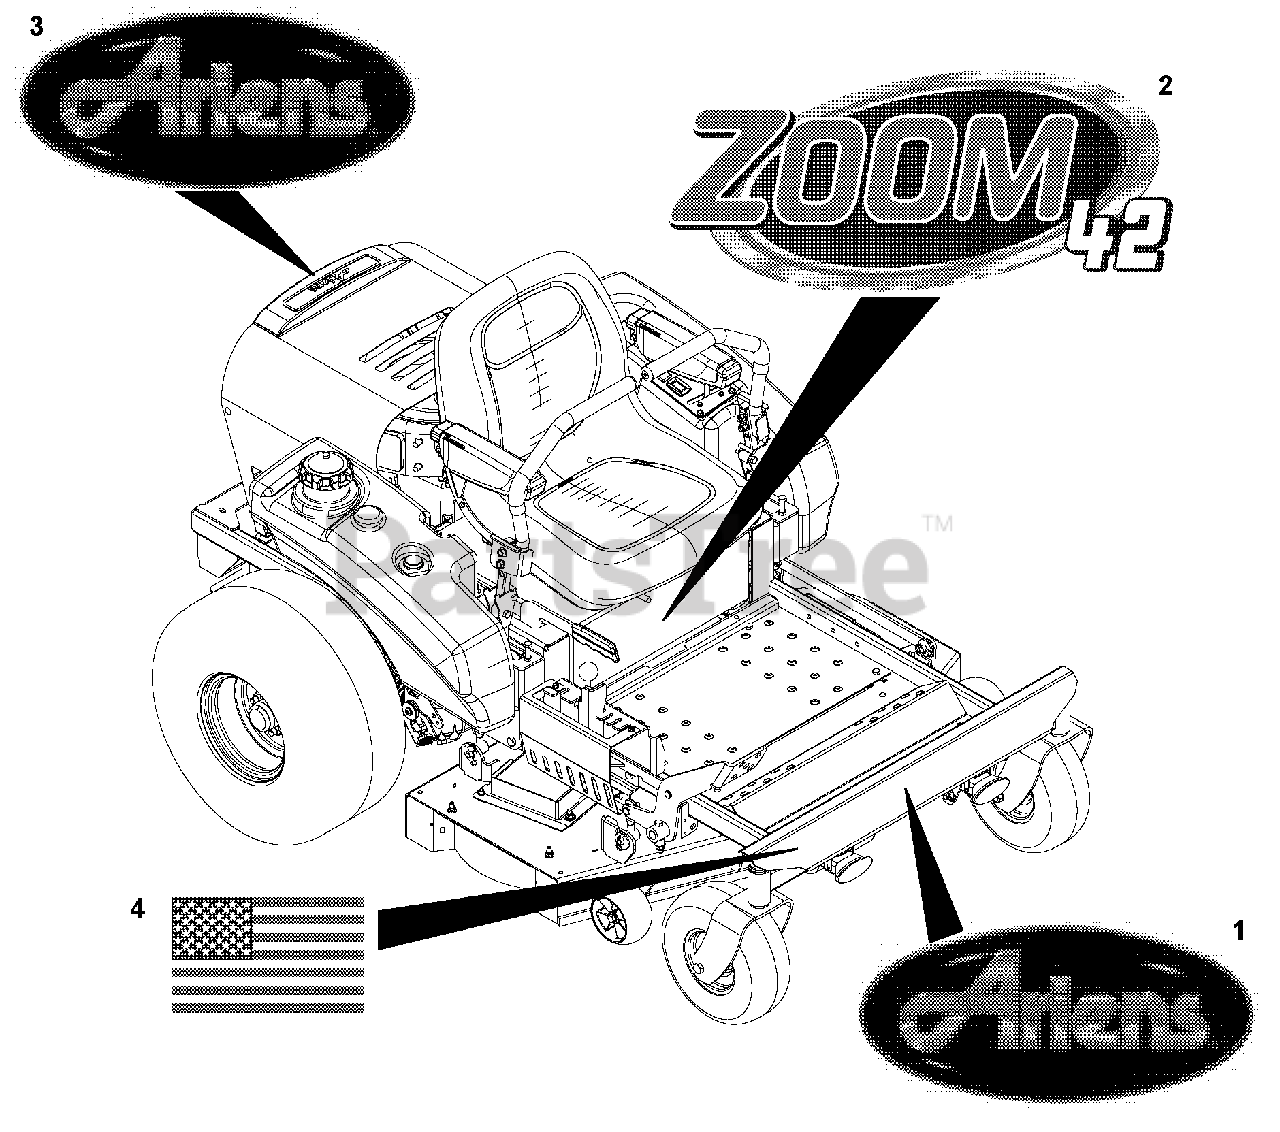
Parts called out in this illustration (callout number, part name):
1	DECAL, ARIENS JEWEL (LARGE)
2	DECAL, ZOOM42
3	DECAL, ARIENS JEWEL
4	DECAL, AMERICAN FLAG
